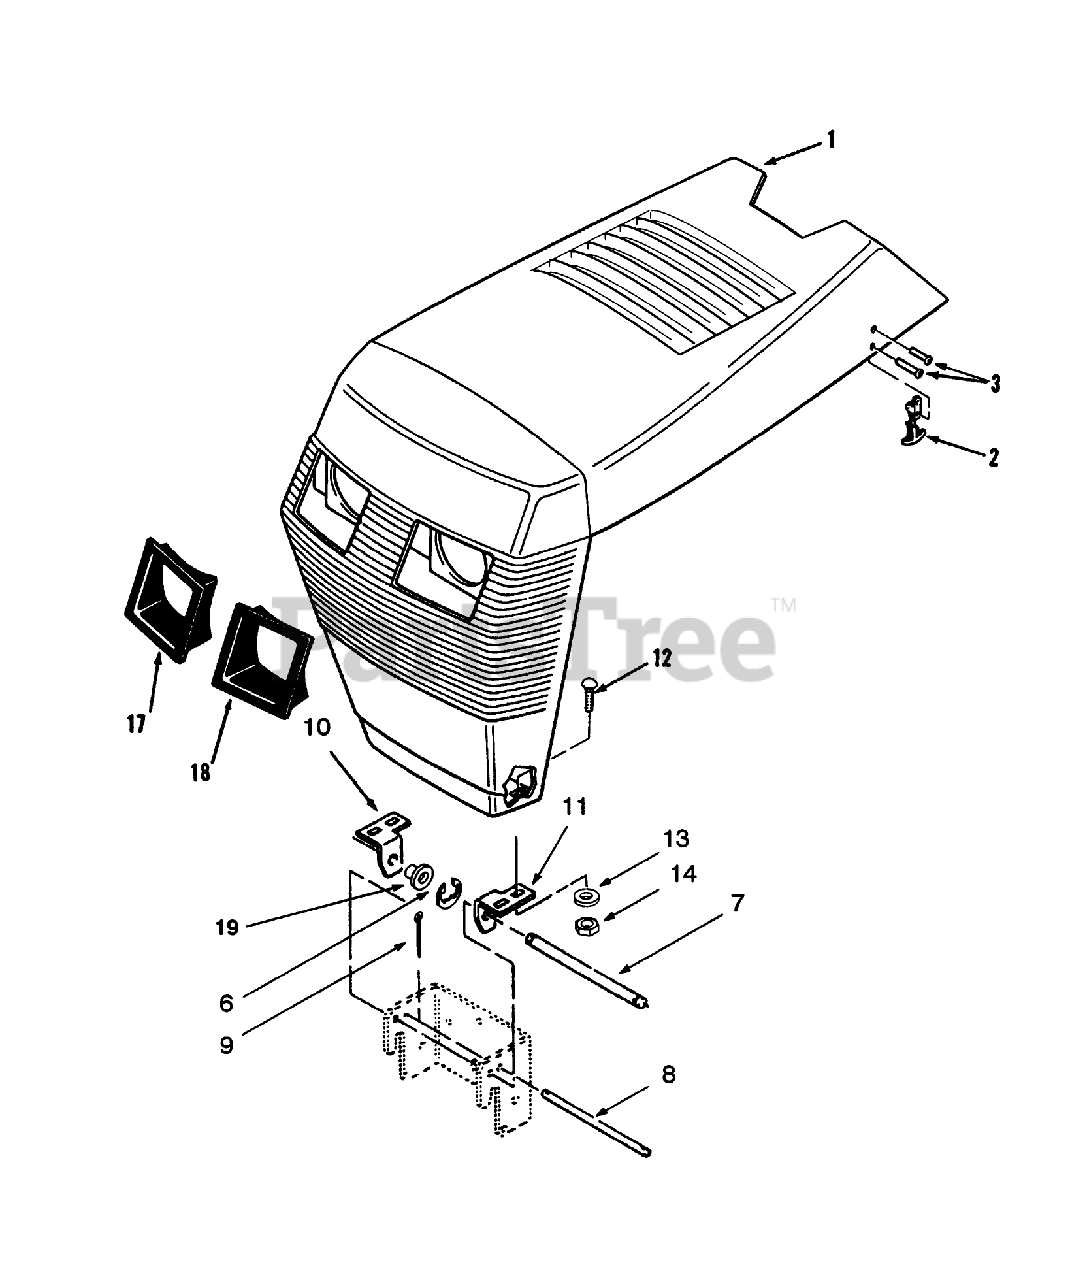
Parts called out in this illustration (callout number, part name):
1	SERV.ASSY-HOOD PKG
3	RIVET-POP
6	RING-RETAINING
7	ROD-GRILL PIVOT
8	ROD-HOOD STOP
10	BRACKET-GRILL, R H
11	BRACKET-GRILL, LH
13	WASHER-FLAT
14	NUT-LOCK, NI
19	BUSHING-NYLINER
